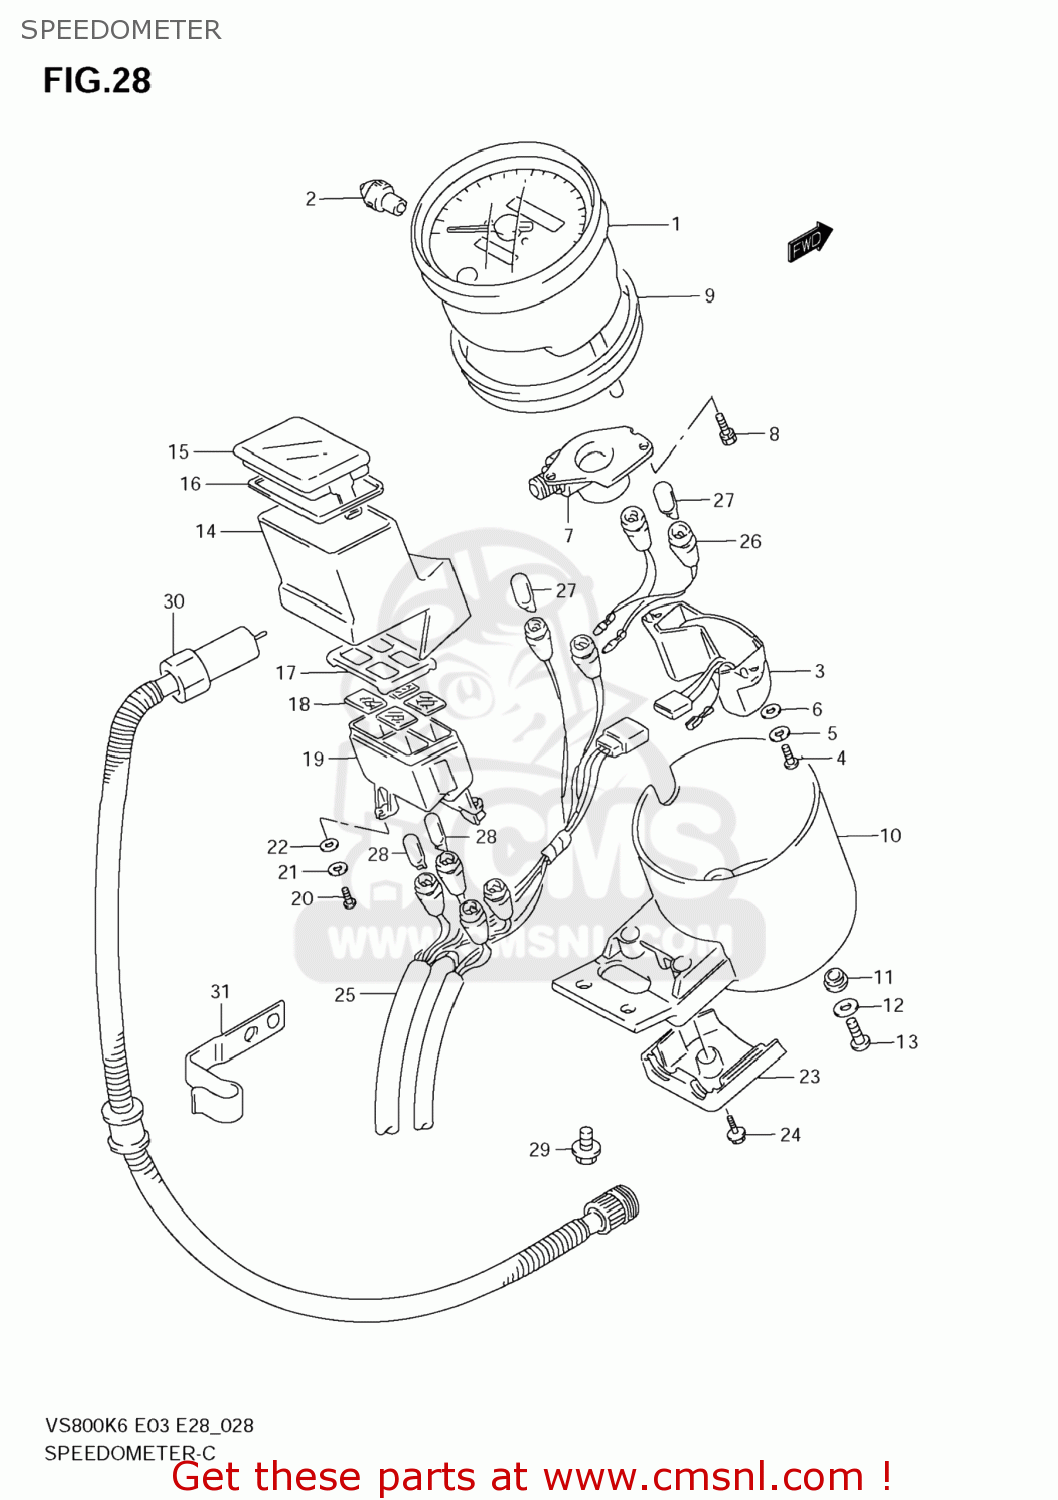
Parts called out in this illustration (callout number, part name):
1	SPEEDOMETER
2	KNOB,TRIP
3	UNIT,WATER TEMP
4	SCREW
5	WASHER,LOCK
6	WASHER
7	BOX,GEAR
8	SCREW
9	CUSHION
10	COVER,METER
11	CUSHION,METER
12	WASHER
13	SCREW
14	BOX,PILOT
15	LENS,PILOT BOX
16	CUSHION
17	PLATE,PILOT LENS
18	LENS SET,PILOT LAMP
19	CASE,PILOT LAMP
20	SCREW
21	WASHER,LOCK
22	WASHER
23	COVER,PILOT BOX
24	SCREW
25	SOCKET,METER NO.1
26	SOCKET
27	BULB(12V3W,T6.5)
28	BULB(12V1.7W,T6.5)
29	SCREW
30	CABLE ASSY,SPEEDOMETER
31	GUIDE,SPEEDOMETER CABLE
